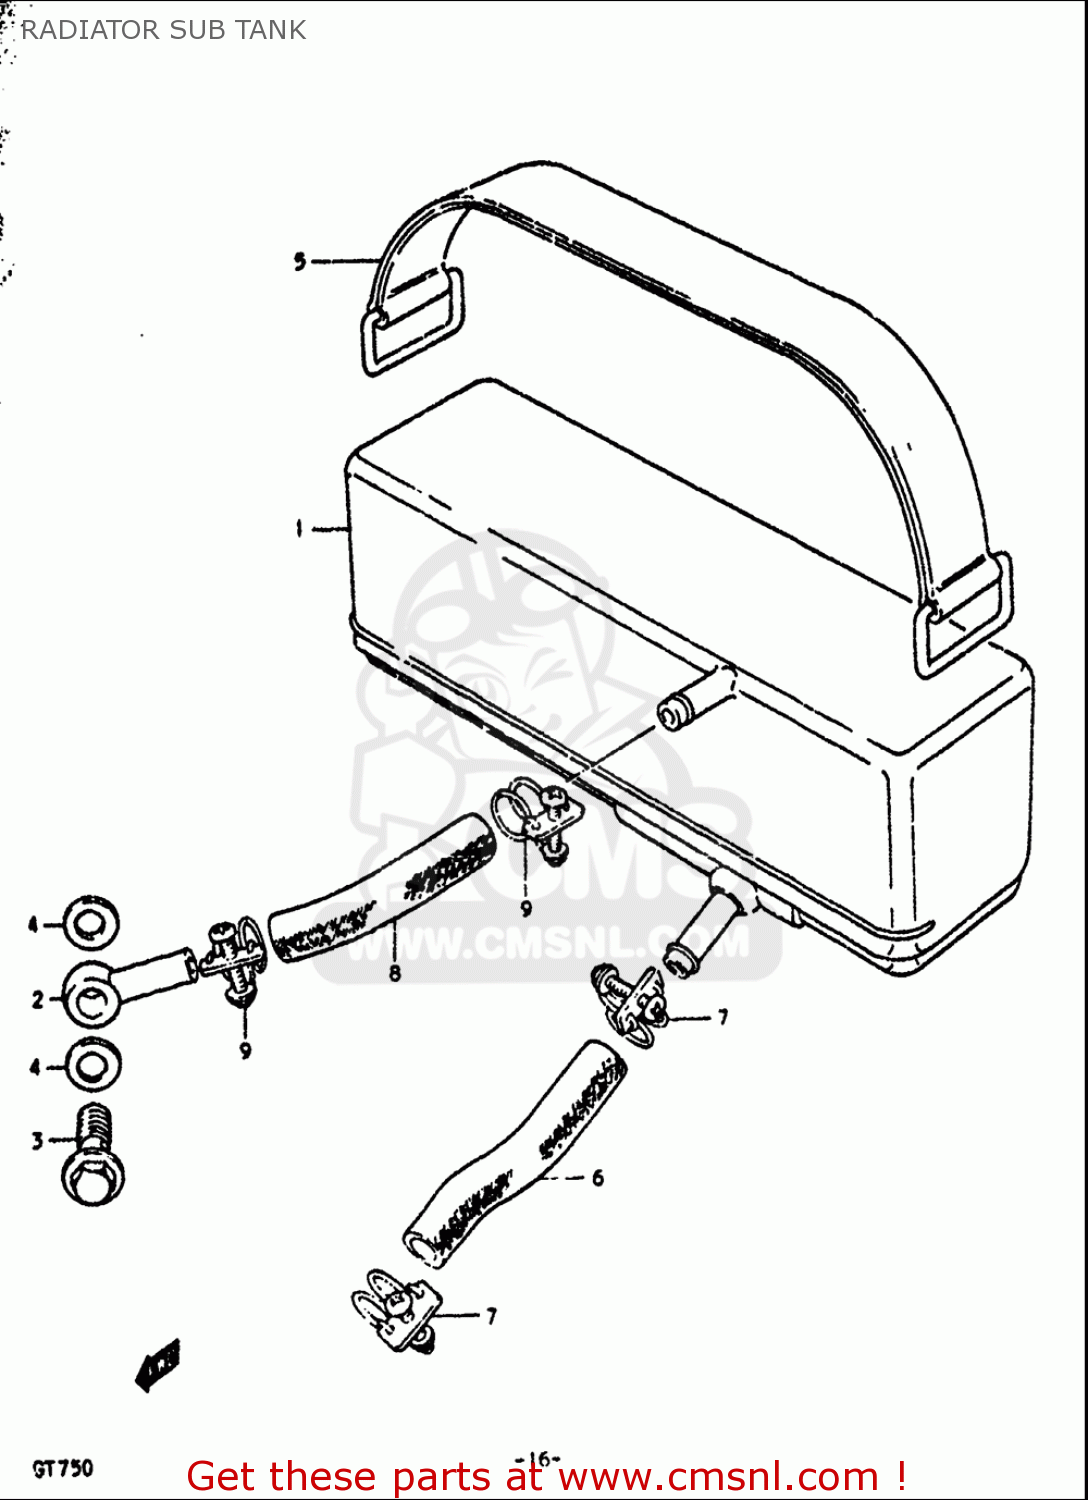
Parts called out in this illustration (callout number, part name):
2	UNION
3	UNION BOLT
4	GASKET(6.2X11X1).2 (NAS)
5	BAND
6	HOSE(5.5X9.5X400)
7	CLAMP
8	HOSE(5.5X9.5X52)
9	CLAMP
